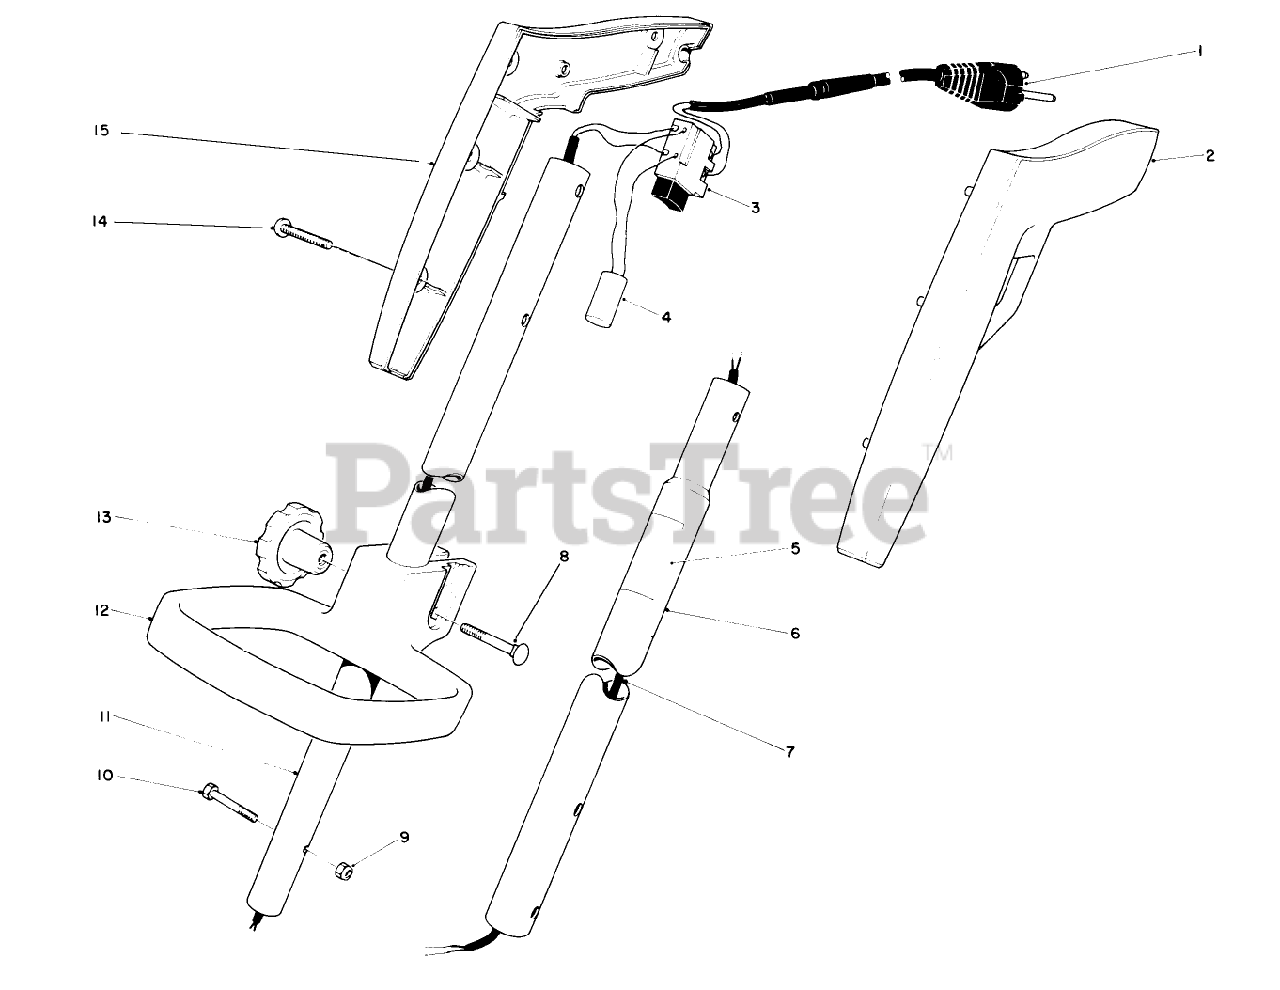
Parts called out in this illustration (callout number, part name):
1	Power Cord
2	Grip-Left Hand
3	Switch
4	Suppressor
5	Caution Decal
6	Tube-Lower
7	Wiring Harness
8	BOLT-CARR
9	NUT-LOCK, NI
10	HEX HD MACHINE SCREW
11	Tube-Upper
12	ADJUSTABLE HANDLE
14	Screw
15	Grip-Right Hand
